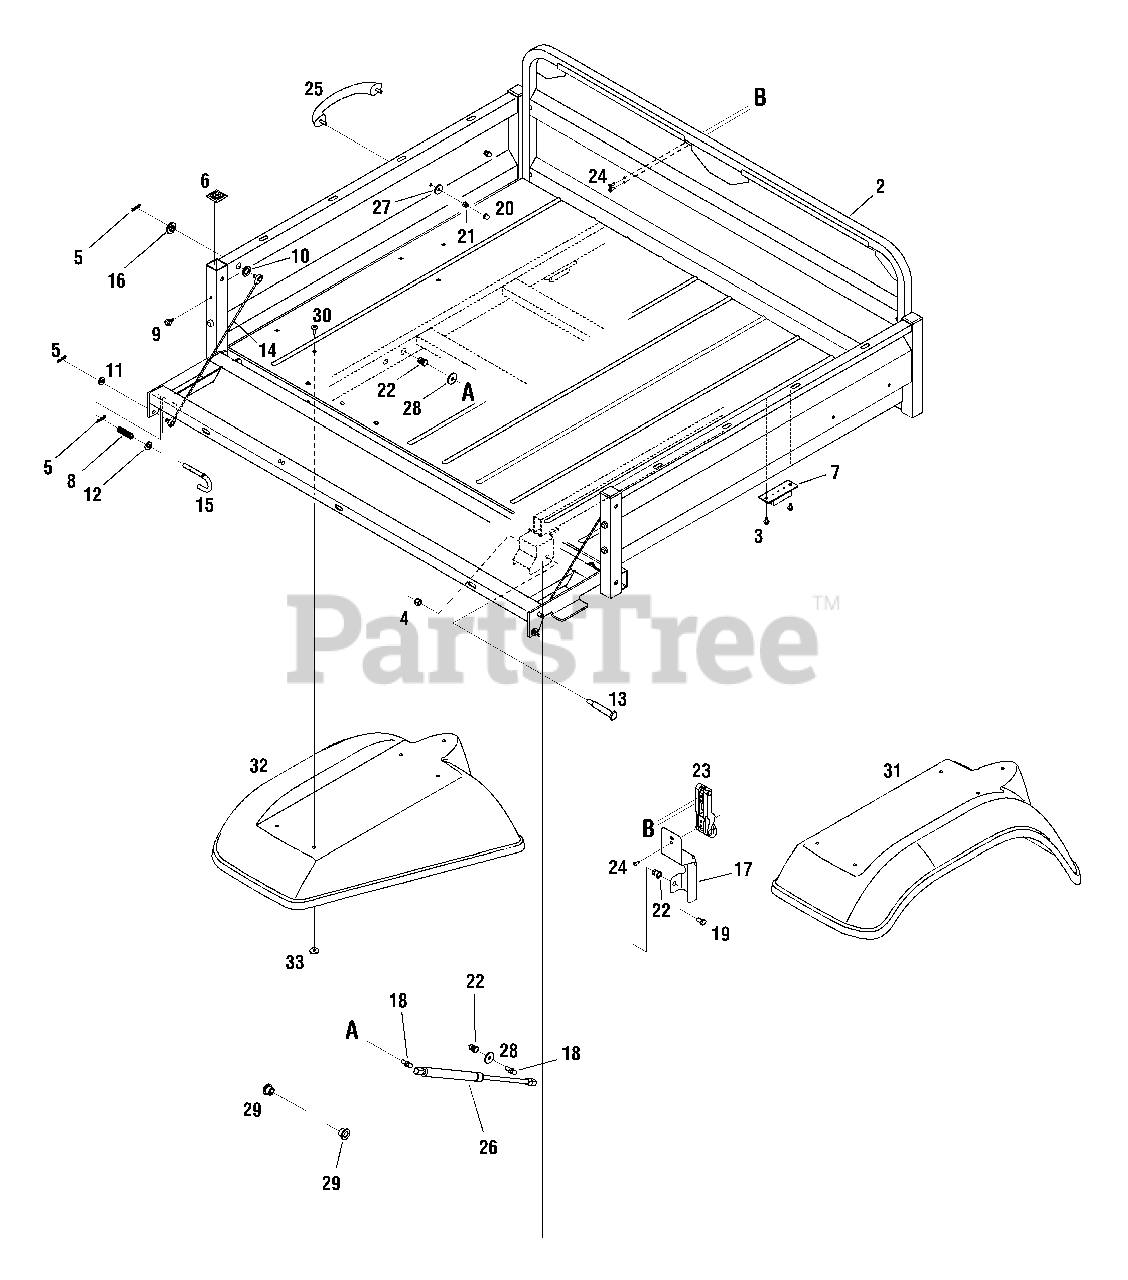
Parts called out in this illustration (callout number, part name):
1	Tailgate Assembly
2	Bed Assembly
3	Screw, Self-tapping, 1/4-20 x 0.500
4	Nut, Nylon Hex Lock, 3/8-16
5	Cotter Pin, .072 Dia x 1.13
7	Bumper, Extension Suspension
8	Compression Spring, .406 x .531 x
9	Bumper, .62Dia x .3
10	Washer, Flat, .64 ID x 1.0 x .12
11	Washer, Flat, .344 x .750 x .120
12	Washer, Flat, .407 x .812 x .135
13	Screw, Shoulder, 1/2 x 2.5
14	Cable, LIft 16.16 LG
15	Handle, Deck Release
16	Spacer, Shoulder .625 Dia x .324 Dia
17	Bracket, Bed Latch Base
18	Stud, Ball 5/16-18
19	Hex Screw, 5/16-18 x .625, Gr5
20	Nut, Acorn 1/4-20 w/o Lock
21	Nut, Hex Lock, 1/4-20
22	Nut, Insert 5/16-18
24	Pop Rivet, 3/16
25	Handle, Bag w/Screw
26	Spring, Gas .91 Stroke
27	Washer, Flat .265 x .938 x .120
28	Washer, Flat .344 x 1.125 x .120
29	Flange Bearing, .51
30	Pop Rivet, .188
31	Fender, Rear RH, Yellow
32	Fender, Rear LH, Yellow
33	Flat Washer, .194 x .62 x .063
